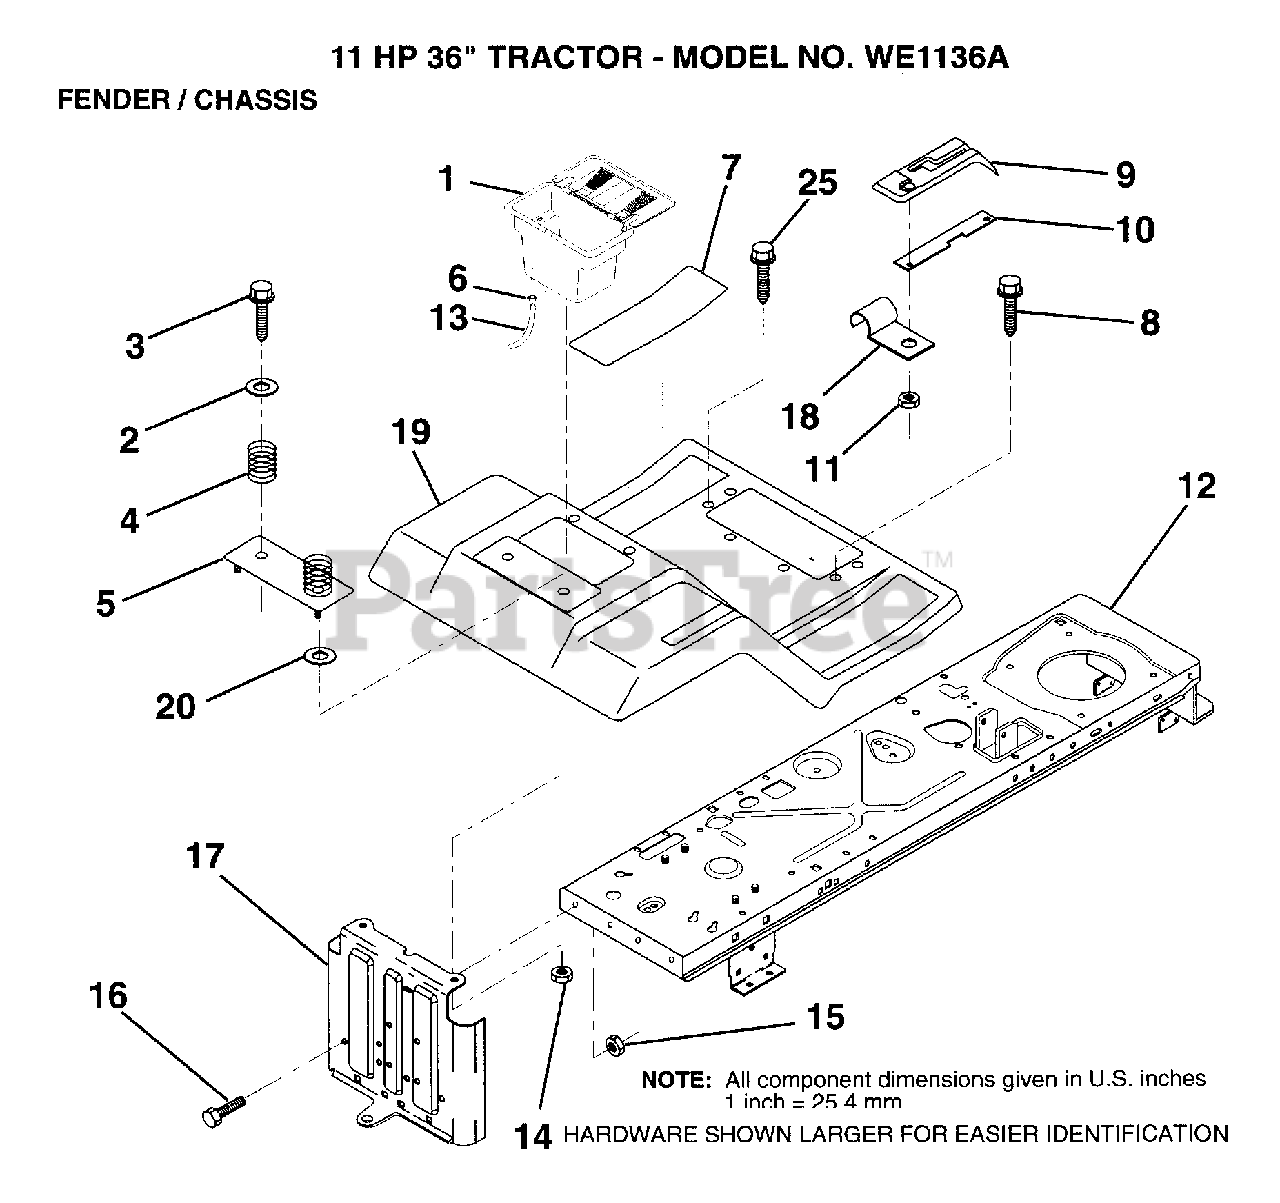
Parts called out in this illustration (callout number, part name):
2	WASHER
3	SCREW
4	SPRING COMPRESSIO
5	PLATE, BATTERY
6	HOSE CLAMP T
7	PAD FOOTREST
8	SCREW
9	CONSOLE SHFT 5SP
11	NUT
13	TUBE T
14	NUT
16	BOLT
17	DRAWBAR
18	"CLIP,INSULATOR"
25	SCREW TI
